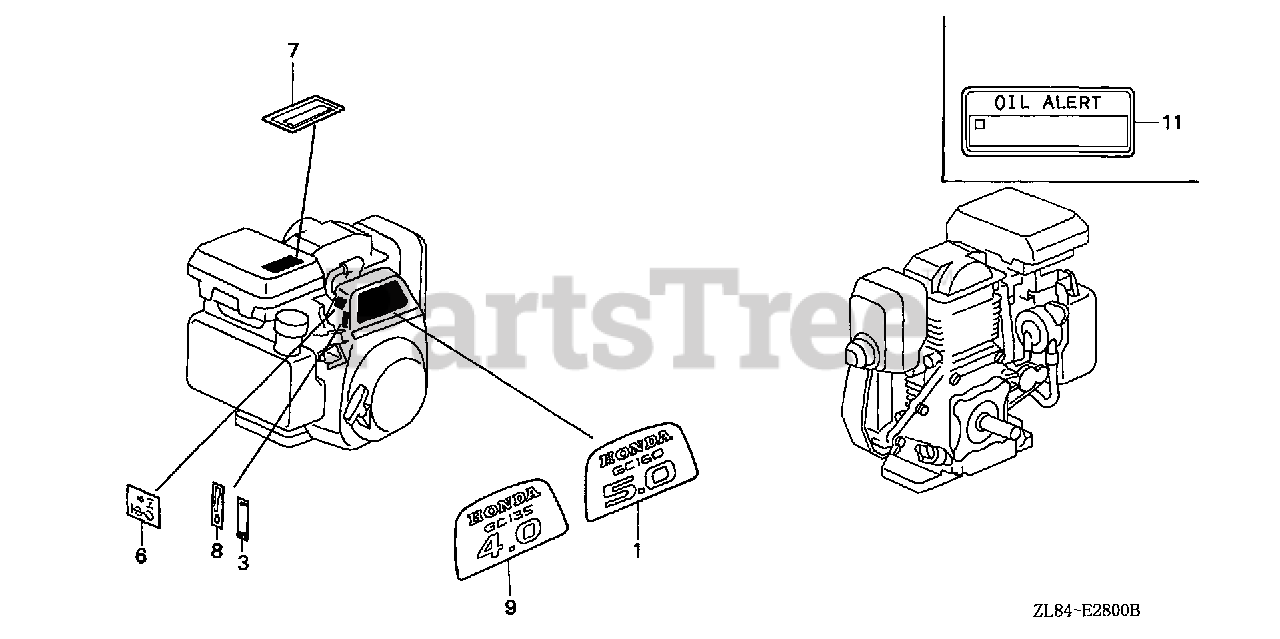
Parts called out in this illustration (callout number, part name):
1	MARK, EMBLEM (5.0)
6	MARK, CHOKE
7	MARK, OIL ALERT (E)
8	MARK, THROTTLE INDICATION
